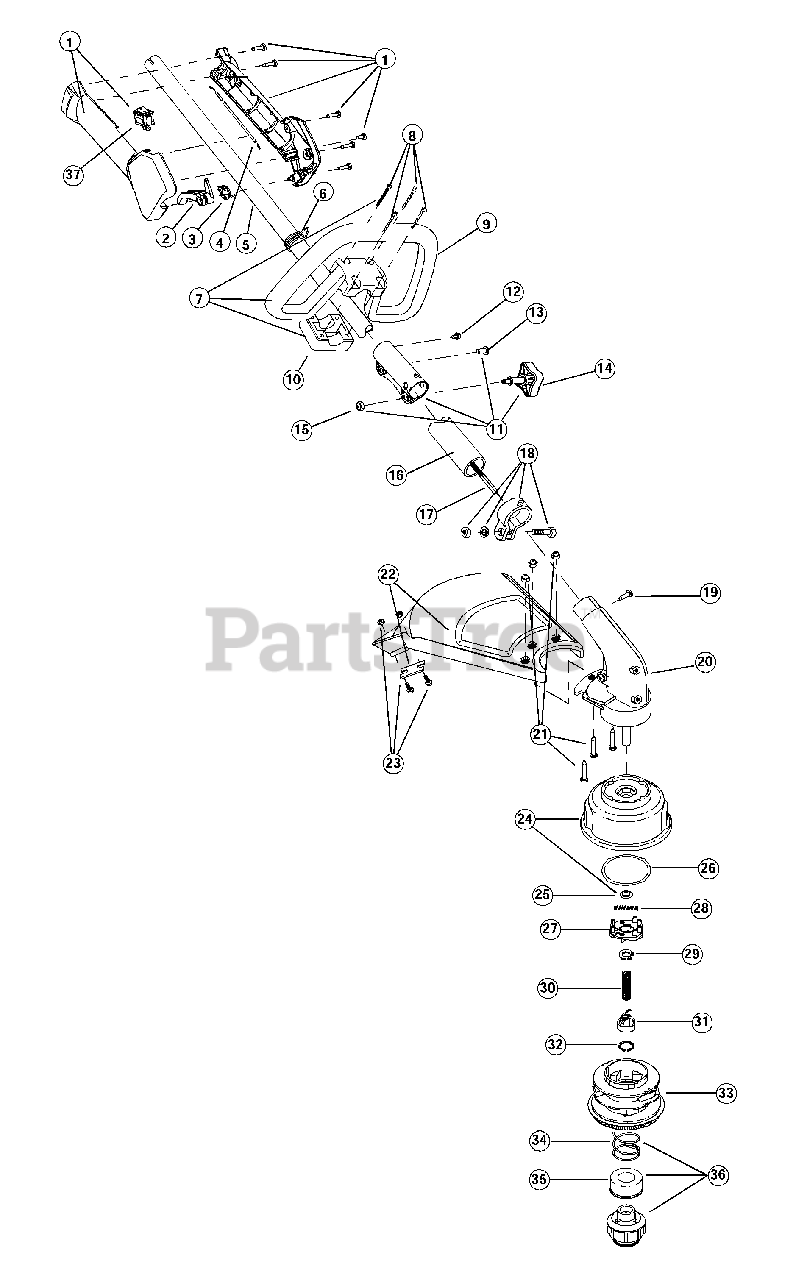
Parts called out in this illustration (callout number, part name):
1	Throttle Housing Assembly
2	Throttle Trigger
3	Throttle Trigger Spring
4	Throttle Cable Assembly
5	Upper Drive Shaft Housing Assembly
6	Harness Clip
7	Deluxe D-Handle Assembly
9	Deluxe D-Handle
10	Bottom Clamp
11	EZ-Link (TM) Coupler
14	Adjustment Knob
15	Knob Retaining Bolt
16	Lower Drive Shaft Housing Assembly
17	Lower Flexible Drive Shaft
18	Lower Clamp Assembly
19	Anti-Rotation Screw
20	Gear Box Assembly
21	Shield Mounting Hardware
22	Shield and Blade Assembly
23	Blade Assembly
24	Outer Spool and Eyelet Assembly w/ Retainer
26	Thrust Washer
28	Small Spring
33	Inner Reel
34	Large Spring
36	Bump Head Knob Assembly
